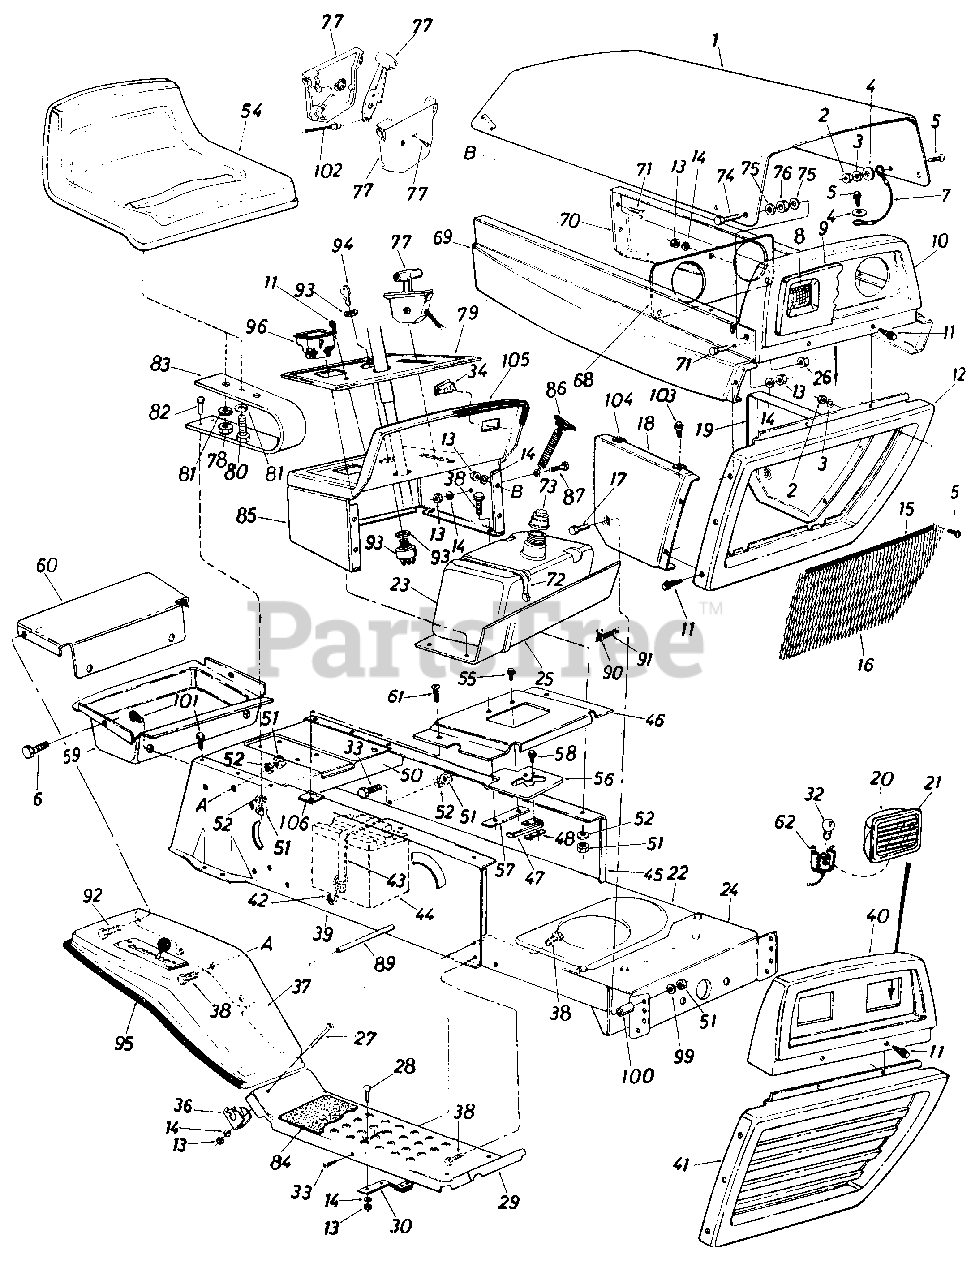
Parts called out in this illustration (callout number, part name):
3	L-Wash. #10 I.D.
4	Fl-Wash. .25" I.D. x .62"
5	Truss Scr. #10-24 x .375"
6	Truss Hd. Scr. #10-24 x .50"*
7	Hood Stop
8	Headlight Optional Part
9	Headlight Bezel Optional Part
10	Front Grille Upper Ass'y. Optional Part
11	Hex AB-Tap Scr. #10 x .50"
12	Lower Grille Optional Parts
13	Hex Nut 1/4-20 Thd.
14	L-Wash. 1/4" 1 D.
15	Vinyl "U"-Channel Optional Part
16	Grille Screen Optional Parts Optional Part
17	Hex Bolt 5/16-18 x 1.50"
18	R.H. Lower Side Panel
19	L.H. Lower Side Panel
20	Headlight Housing Optional Part
21	Headlight Lens Optional Part
22	Lower Frame
23	Fuel Tank
24	Front Pivot Brkt.
25	Fuel Tank Support
26	Hex Cent. L-Nut 3/8-16 Thd.
27	Truss Hd. Scr. 1/4-20 x 1.75"
28	Carriage Bolt 1/4-20 x .62"
29	Running Board
30	Blade Brake Ass'y.
32	Head Lamp Optional Part
33	Truss Mach. Scr. 5/16-18 x .75" Lg.
34	Light Switch Optional Part
36	Fender Clamp
37	Fender
39	R.H. Side Frame
40	Front Upper Grille Ass'y. Optional Part
43	Battery Hold Down Strap
44	12-V Battery
45	L.H. Side Frame
46	Shift Cover
47	Reverse Safety Switch
48	Insulator Nut Plate
50	Hitch Plate
51	Hex Nut 5/16-18 Thd.
52	L-Wash. 5/16" I.D.
54	Seat Ass'y.
55	Truss Mach. Scr. 1/4-20 x .75" Lg.
56	Gear Selection Plate
57	Clamping Plate
58	Hex AB-Tap Scr. #8 x .50"
59	Tool Tray
62	Head Lamp Socket Optional Part
68	Head Lamp Retainer Optional Part
69	Side Panel-R.H.
70	Side Panel-L.H.
71	Hex Bolt 1/4-20 x .62" Lg.
72	Tie Strap
73	Fuel Cap Gauge
74	Hex Bolt 3/8-16 x 1.00" Lg.
75	Fl-Wash. .380" I.D. x 1.00"
76	Rubber Wash. .33" I.D. x .87" O.D.
77	Throttle Control Box Ass'y.
78	Hex Nut 1/2-13 Thd.
79	Dash Panel Insert
80	Hex Bolt 1/2-13 x 1.00" Lg.
81	L-Wash. 1/2" I.D.
82	Hex Bolt 5/16-18 x 1.00"*
83	Seat Spring
84	Foot Pad
87	Hex Bolt 1/4-20 x .50" Lg.
89	Running Board Rod
90	Hose Clamp
91	Fuel Line
92	Thread Rolling Scr. 1/4-20 x .50" Lg.
93	Ignition Switch
94	Ignition Key
95	Trim Strip
96	Ammeter
99	Belleville Wash. .34" I.D.
100	Spacer.344" I.D. x 1.0" O.D. x .75" Lg.
101	Hex Wash. Hd. AB-Tap Scr. 5/16 x .75" Lg.
102	Throttle Control Wire
103	Hex Wash. Hd. Self-Tap Scr.
104	Speed Nut #10Z
105	Trim Strip-15"
106	Speed Nut #10
